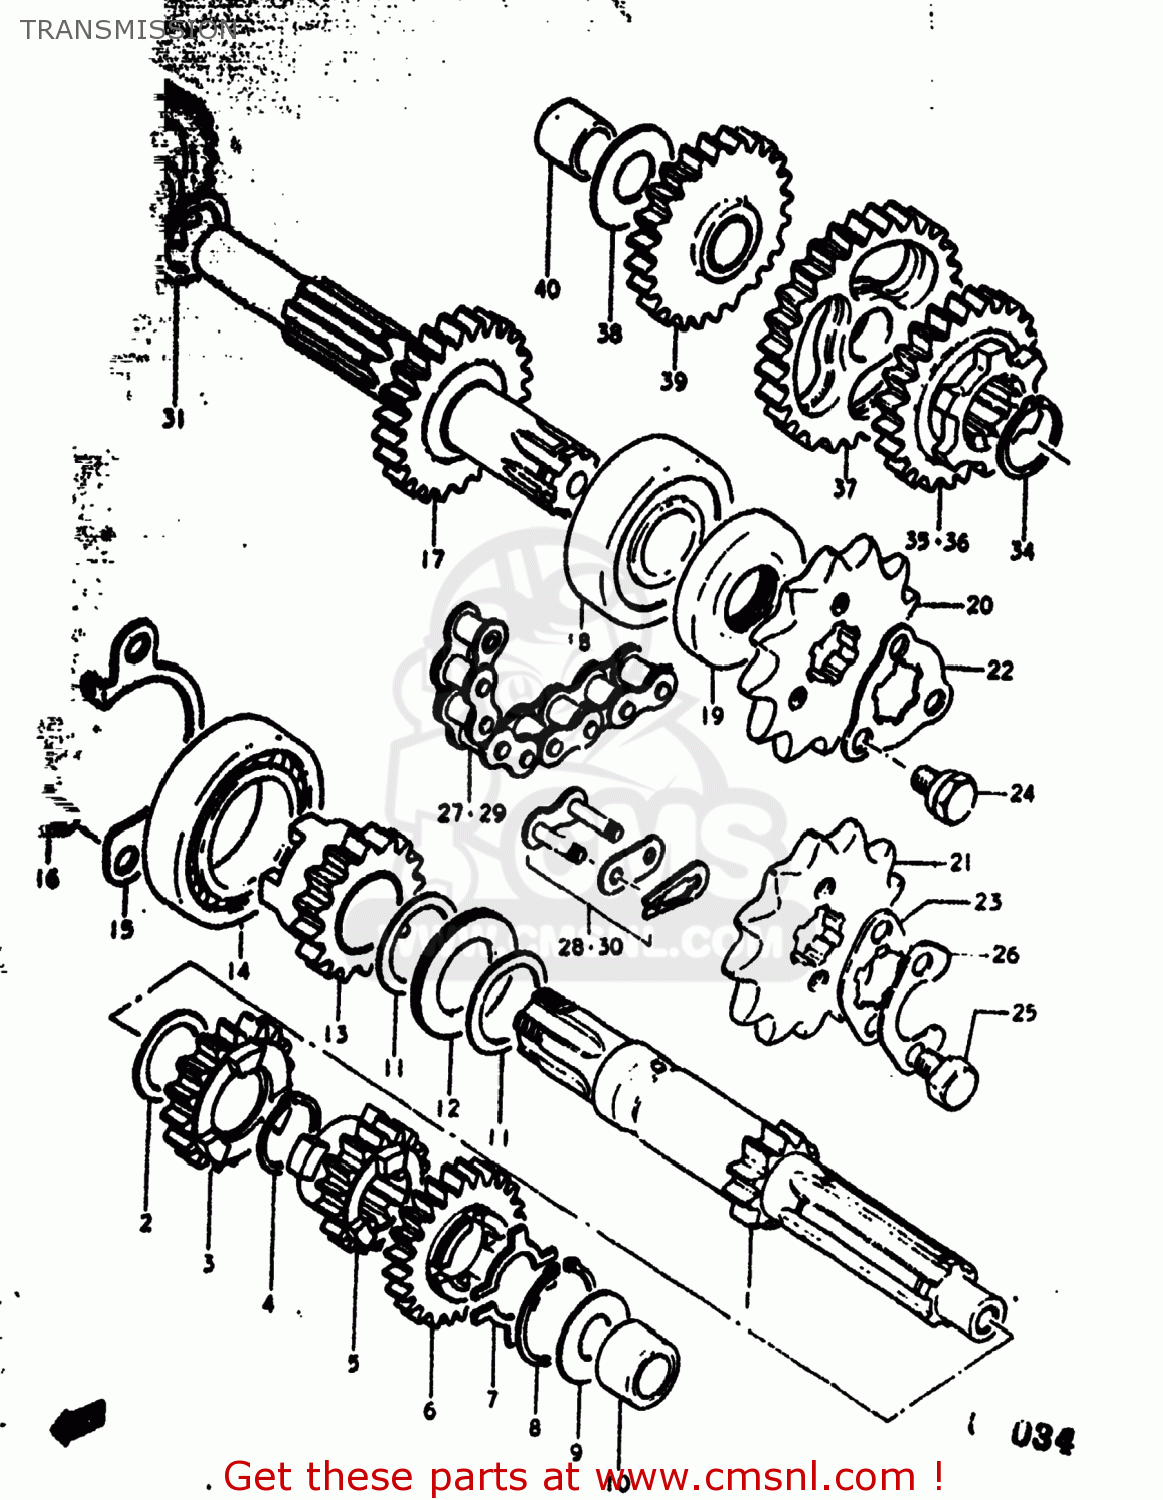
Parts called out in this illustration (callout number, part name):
1	SHAFT,COUNTER
2	WASHER
3	GEAR,THIRD DRIVE
4	CIRCLIP
5	GEAR,SECOND DRIVE
6	GEAR,FOURTH DRIVE
7	RING
8	RING,SNAP
9	WASHER
10	BUSH(12X19X11)
11	WASHER(21X30X0.8)
12	BEARING(21X32X2.85)
13	GEAR,KICK STARTER DRIVE
14	BEARING
15	RETAINER,COUNTER SHAFT
16	SCREW
17	SHAFT,DRIVE
18	Bearing
19	SEAL,OIL(20X40X7)
20	SPROCKET,ENGINE
21	SPROCKET,ENGINE
22	SPACER,ENGINE SPROCKET
23	PLATE
24	BOLT
25	BOLT 6X10
26	LOCK WASHER
27	CHAIN ASSEMBLY,DRIVE
28	JOINT ASSEMBLY,CHAIN
29	CHAIN ASSEMBLY,DRIVE
30	JOINT ASSEMBLY,CHAIN
31	WASHER,THRUST
32	GEAR,SECOND DRIVEN
33	GEAR,SECOND DRIVEN
34	CIRCLIP
35	GEAR,THIRD DRIVEN
36	GEAR,THIRD DRIVEN
37	GEAR,FIRST DRIVEN
38	WASHER
39	GEAR,KICK STARTER IDLE
40	BUSHING
